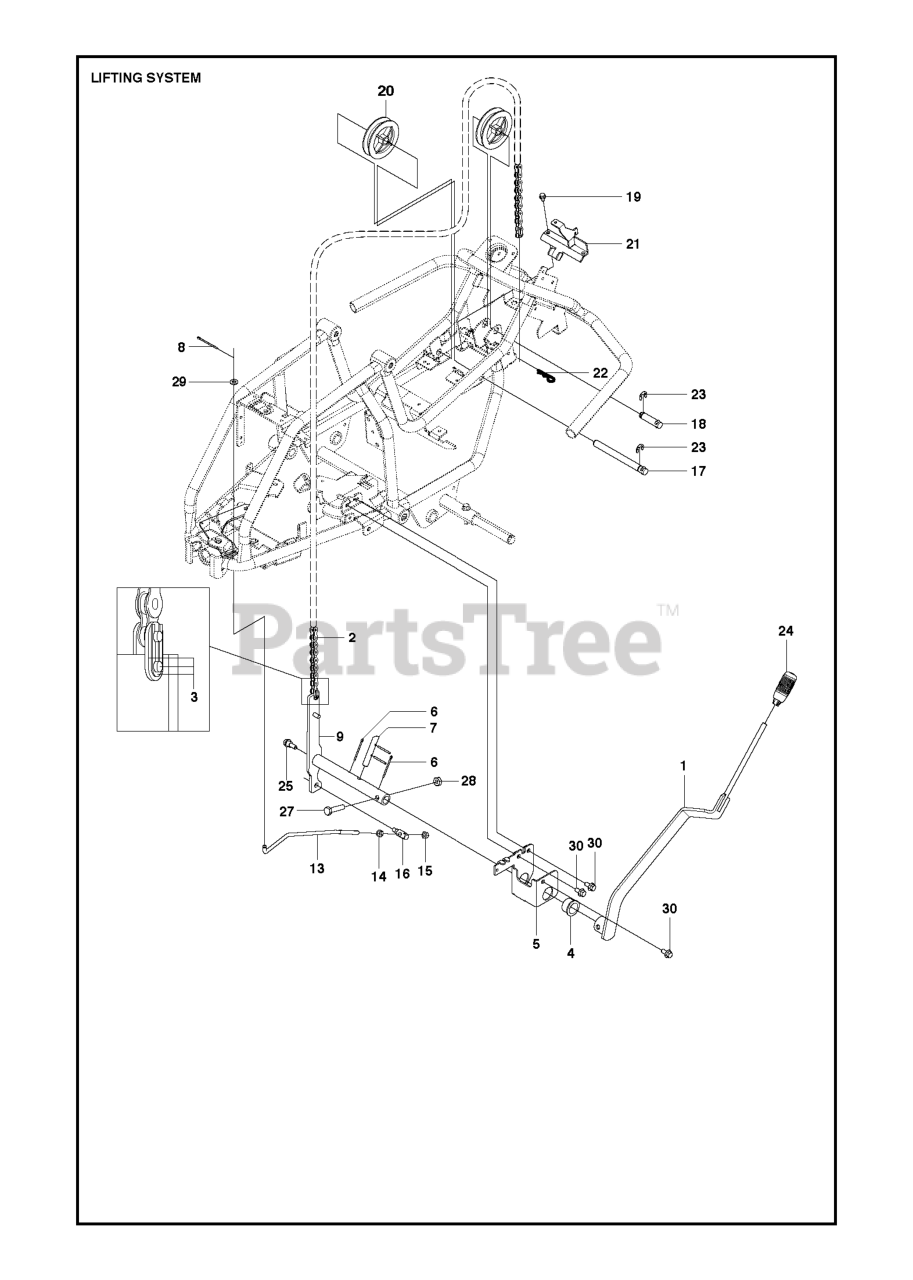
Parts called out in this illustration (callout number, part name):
1	LEVER ASSY
4	BEARING FLANGE
5	BRACKET ASSY
6	COTTER PIN
14	NUT
15	LOCKNUT M8
24	GEAR STICK KNOB
27	REPL BY 725 25 00-71
28	NUT
29	WASHER BRB 8.4X17
